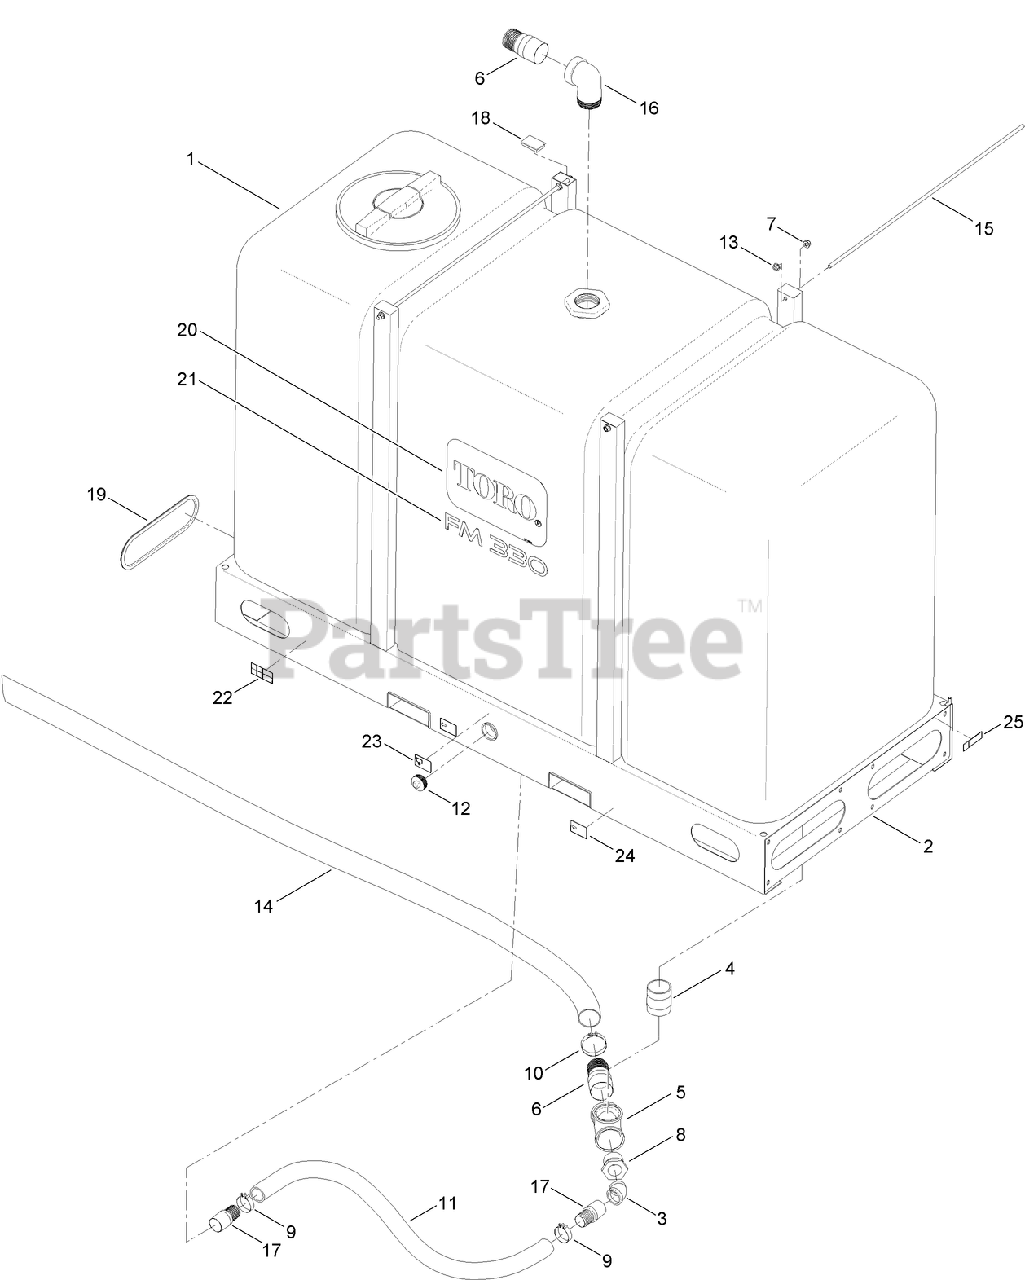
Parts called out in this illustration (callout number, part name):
1	1000 GALLON MIX TANK ASM
2	MIX TANK FRAME ASM
3	ELBOW-PIPE-45
4	NIPPLE-PIPE
5	TEE-PIPE
6	NIPPLE-COMBINATION
7	NUT-LOCK
8	BUSHING-PIPE
9	CLAMP-HOSE, T-BOLT
10	CLAMP-T BOLT
11	HOSE-WATER, SUCTION
12	PLUG-PIPE, SQUARE HEAD
13	NUT-HHF
14	HOSE-SUCTION, WATER
15	BAR-THREADED, STEEL
16	ELBOW-PIPE, 45 DEG
17	NIPPLE-COMBINATION
19	TRIM-FRAME, MIX TANK
22	DECAL-WARNING, MIXER
23	DECAL-DRAIN
24	DECAL-FORKLIFT
25	DECAL-GROUND ROD
